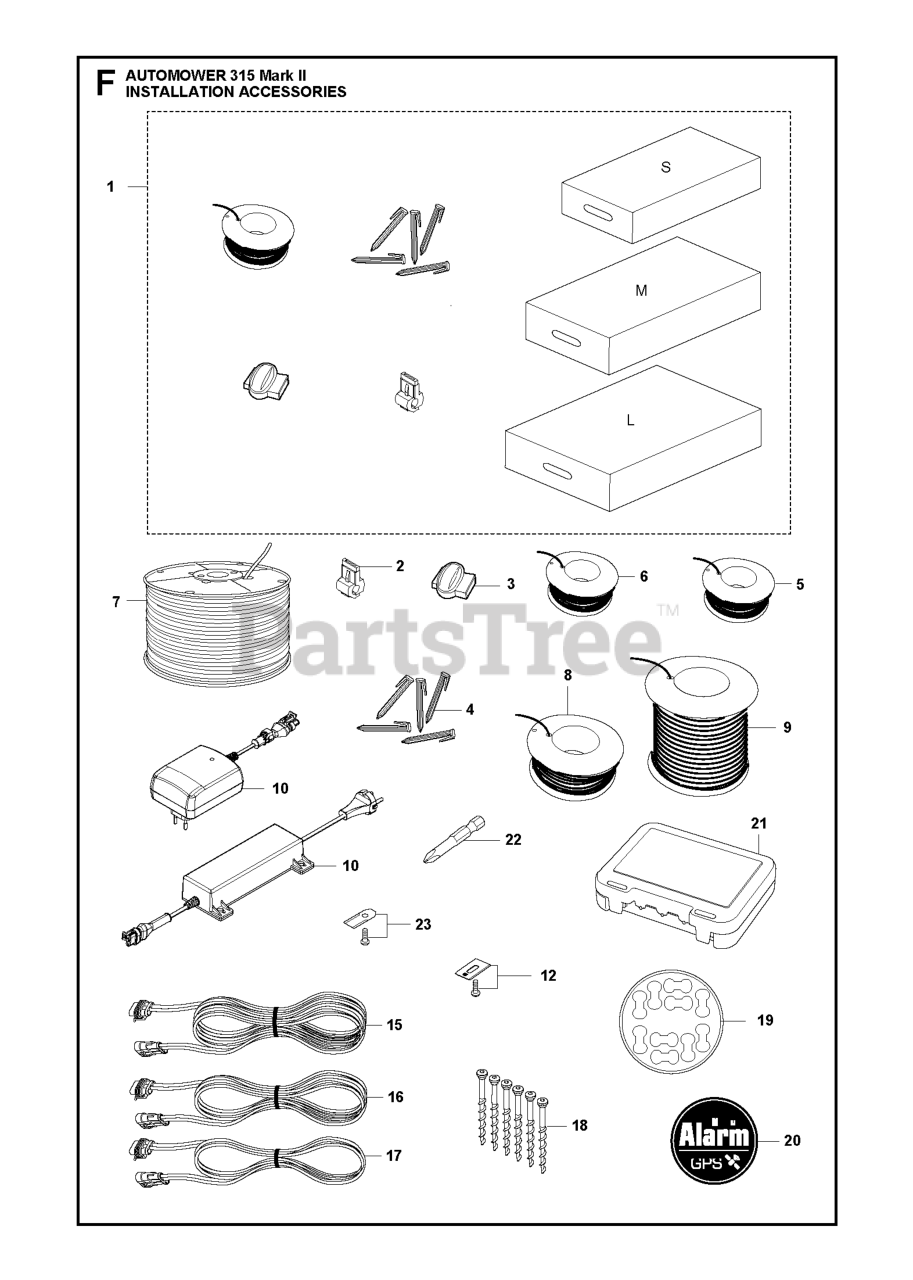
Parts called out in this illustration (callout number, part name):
1	MED AUTOMOWER INSTALL KIT
1	SMALL AUTOMOWER INSTALL KIT
1	LARGE AUTOMOWER INSTALL KIT
2	BRAKER
2	CONNECTOR 100 PCS
2	CONNECTOR 5 PCS, BLISTER
3	COUPLER SPLICER, 100 PCS
3	COUPLER SPLICER, 5 PCS,
3	SPLICE KIT
4	STAPLE 100 PCS, BLISTER
4	STAPLE 100 PCS
5	WIRE BOUNDARY 150M
5	WIRE 150M, BLISTER
5	WIRE 50M STANDARD Ø2.7MM,BLIST
6	WIRE 250M
8	WIRE 500M
9	WIRE (800M)
10	Power Unit
10	POWER UNIT POWER SUPPLY 1,3A
15	CABLE ASSY LOW VOLTAGE CABLE
16	CABLE ASSY LOW VOLTAGE CABLE
17	CABLE ASSY LOW VOLTAGE CABLE
18	Screws
19	STICKER CABLE MARKERS KIT 10PC
20	Decals
21	CONNECTOR PROTECTION BOX
22	WRENCH BITS CHANGING ROBOTIC B
23	HUS BLADE SET 300 PCS
23	HUS BLADE SET 9 PCS
23	HUS BLADE SET 45 PCS
